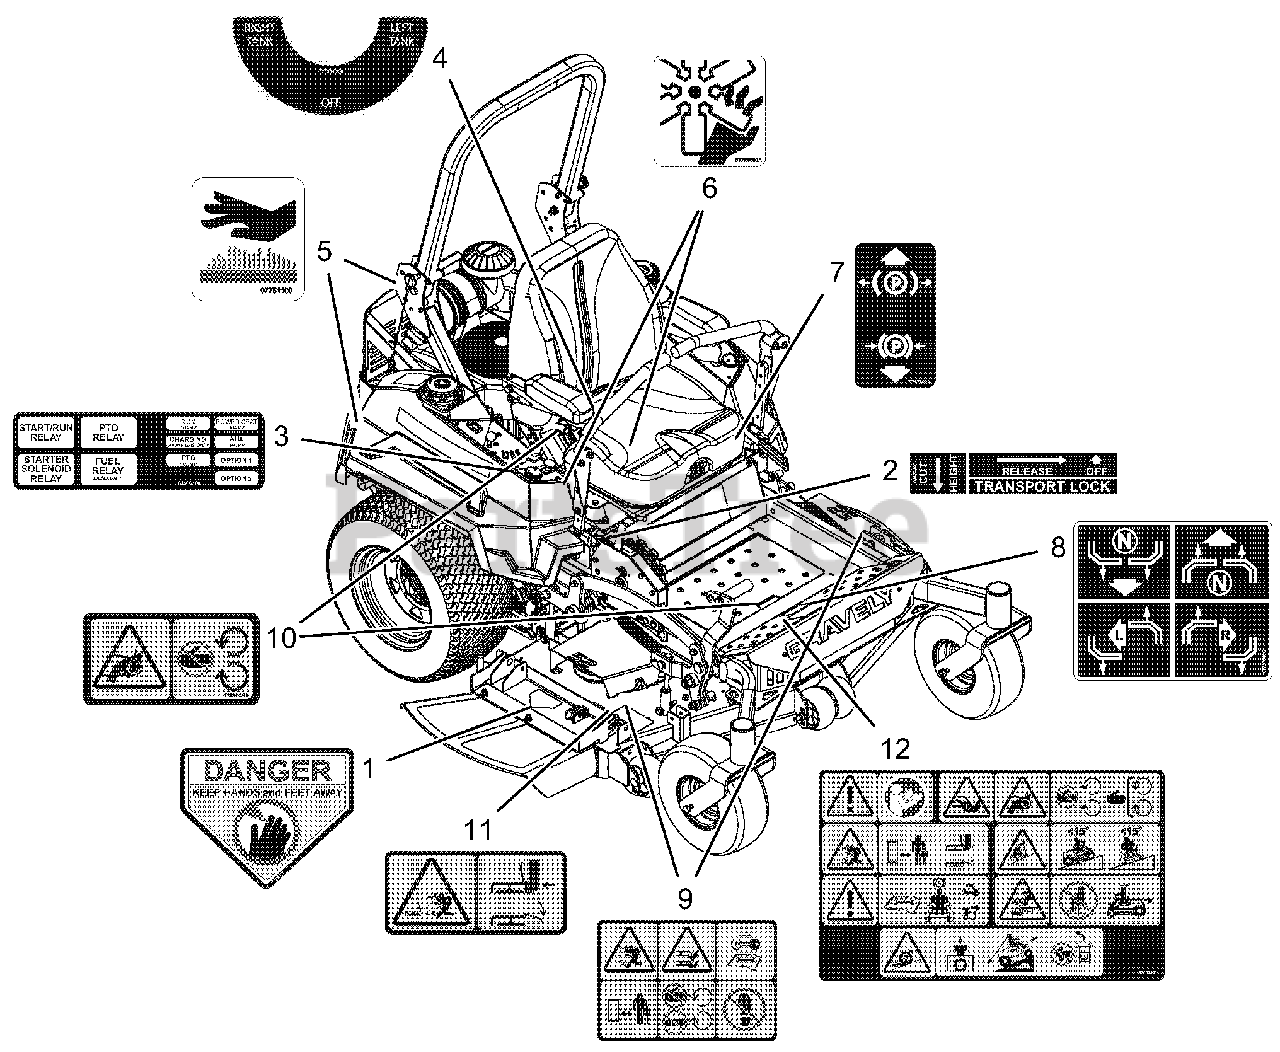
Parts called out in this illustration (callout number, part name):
1	DECAL, DANGER
2	DECAL, TRANSPORT LOCK INSTRUCT
3	DECAL, FUSE BOX
4	DECAL, FUEL CONTROL VALVE
5	DECAL HOT SURFACE
6	DECAL, DANGER - FAN
7	DECAL, PARKING BRAKE LEVER
8	DECAL, INSTRUCTIONAL - STEERING
9	DECAL, SAFETY - MOWER DECK
10	DECAL, SAFETY - GUARDING
11	DECAL, SAFETY - DECK GUARDING
12	DECAL, MAIN SAFETY, COMMERCIAL
